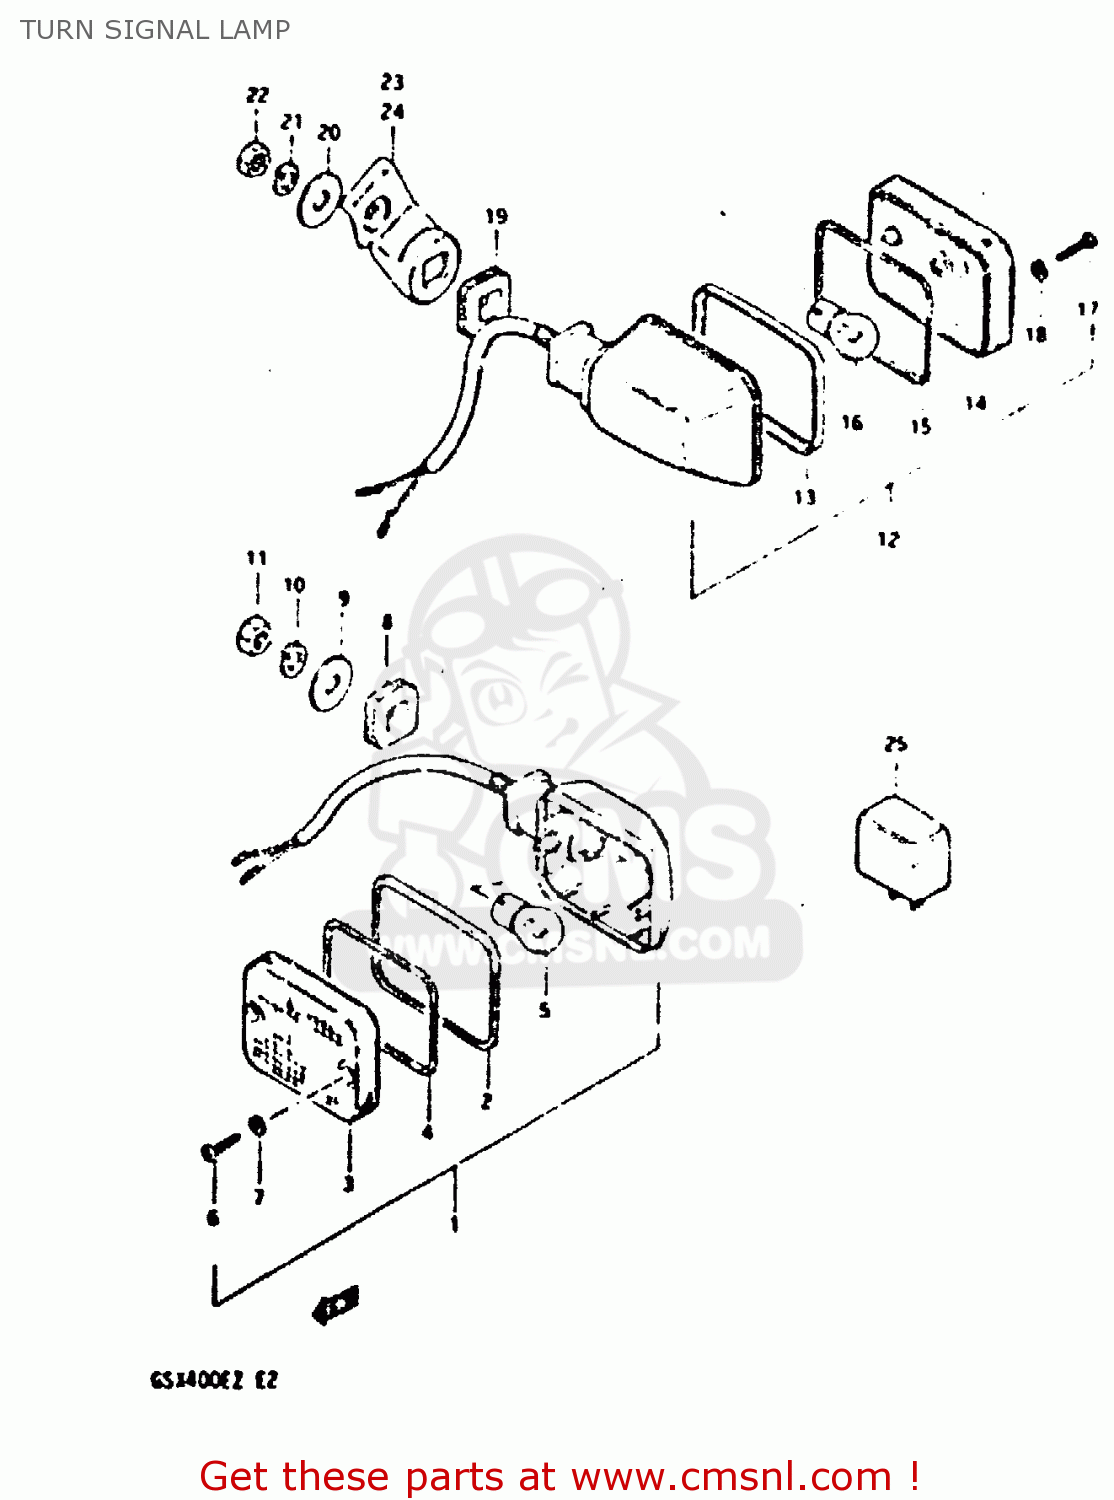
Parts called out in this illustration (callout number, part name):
1	LAMP ASSY,FR T
2	RIM
3	LENS
4	GASKET (NAS)
5	BULB(12V21W)
6	SCREW
7	GASKET (NAS)
8	CUSHION
9	WASHER (10.5X30X2.3)
10	LOCK WASHER
11	NUT
12	LAMP, REAR TURN SIGNAL
13	RIM
14	LENS
15	GASKET (NAS)
16	BULB(12V35/25W,STANLEY,A7025)
17	SCREW
18	GASKET (NAS)
19	CUSHION
20	WASHER (10.5X30X2.3)
21	LOCK WASHER
22	NUT
23	BRACKET,REAR TURN SIGNAL
24	BRACKET,REAR TURN SIGNAL
25	RELAY,TURN SIGNAL
